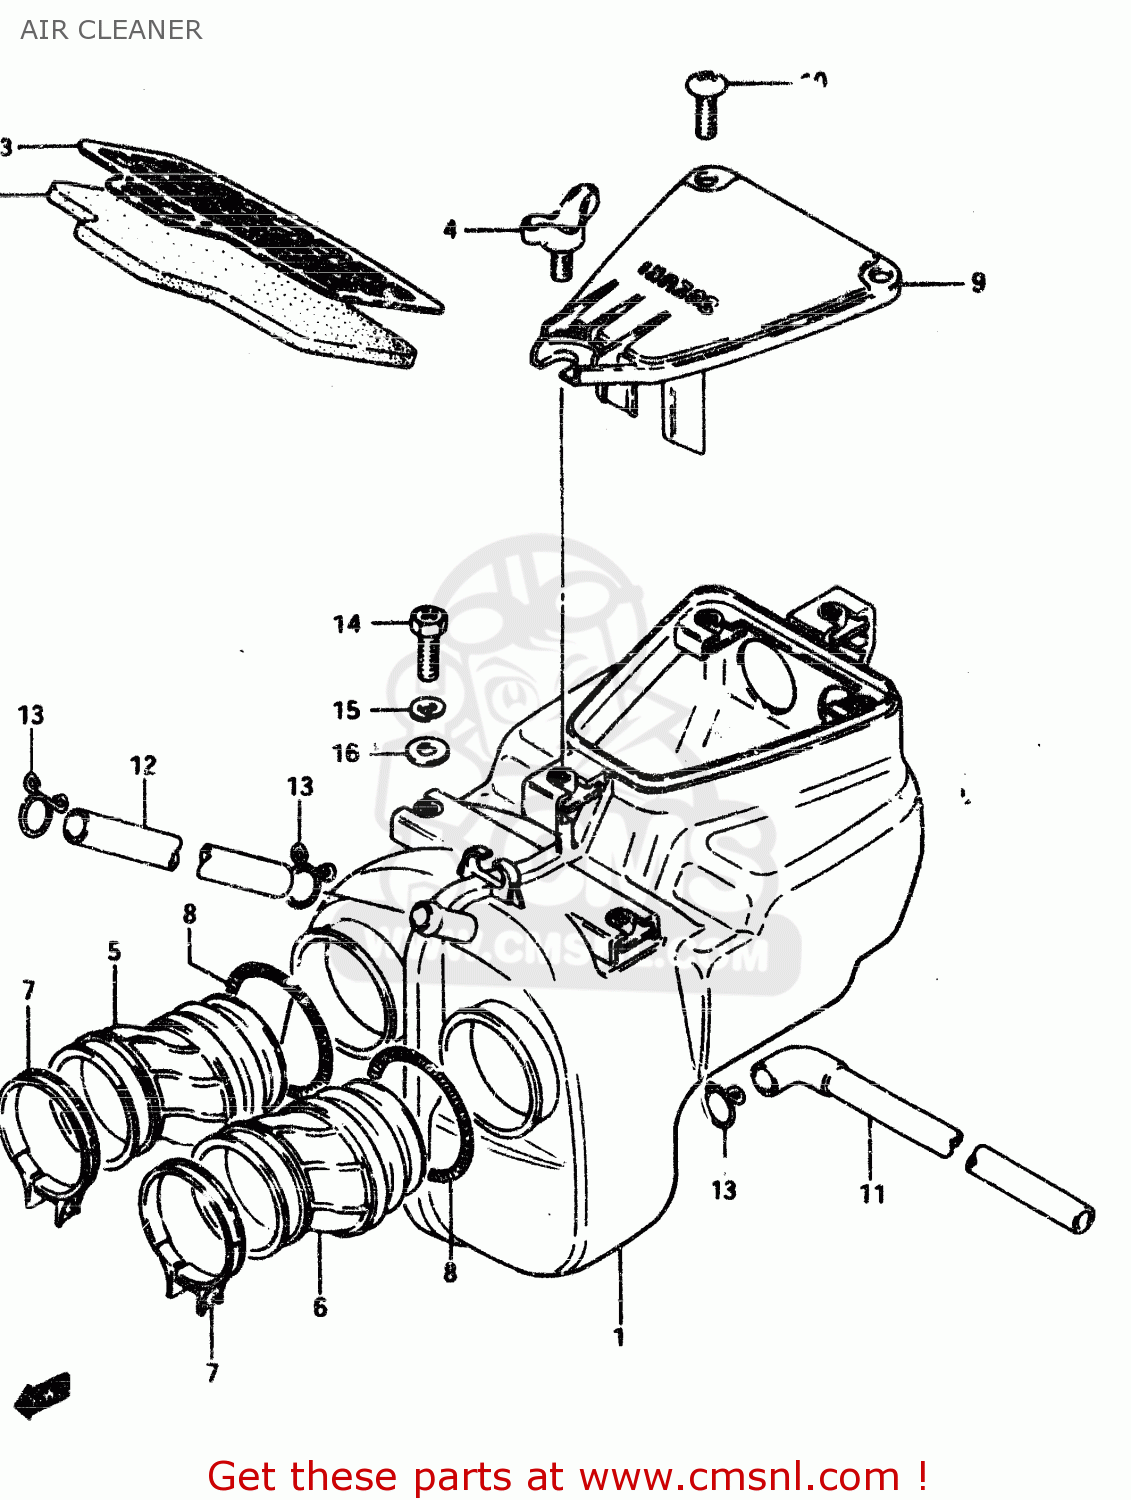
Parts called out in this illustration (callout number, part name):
1	CLEANER ASSEMBLY,AIR
2	FILTER
3	HOLDER,OUTER
4	BOLT, WING
5	TUBE,OUTLET,R
6	TUBE,OUTLET,L
7	CLAMP
8	CLAMP,CLEANER SIDE
9	CAP,AIR CLEANER
10	SCREW
11	DRAIN TUBE
12	TUBE,BREATHER
13	CLAMP
14	SCREW(6X12)
15	LOCK WASHER
16	WASHER
